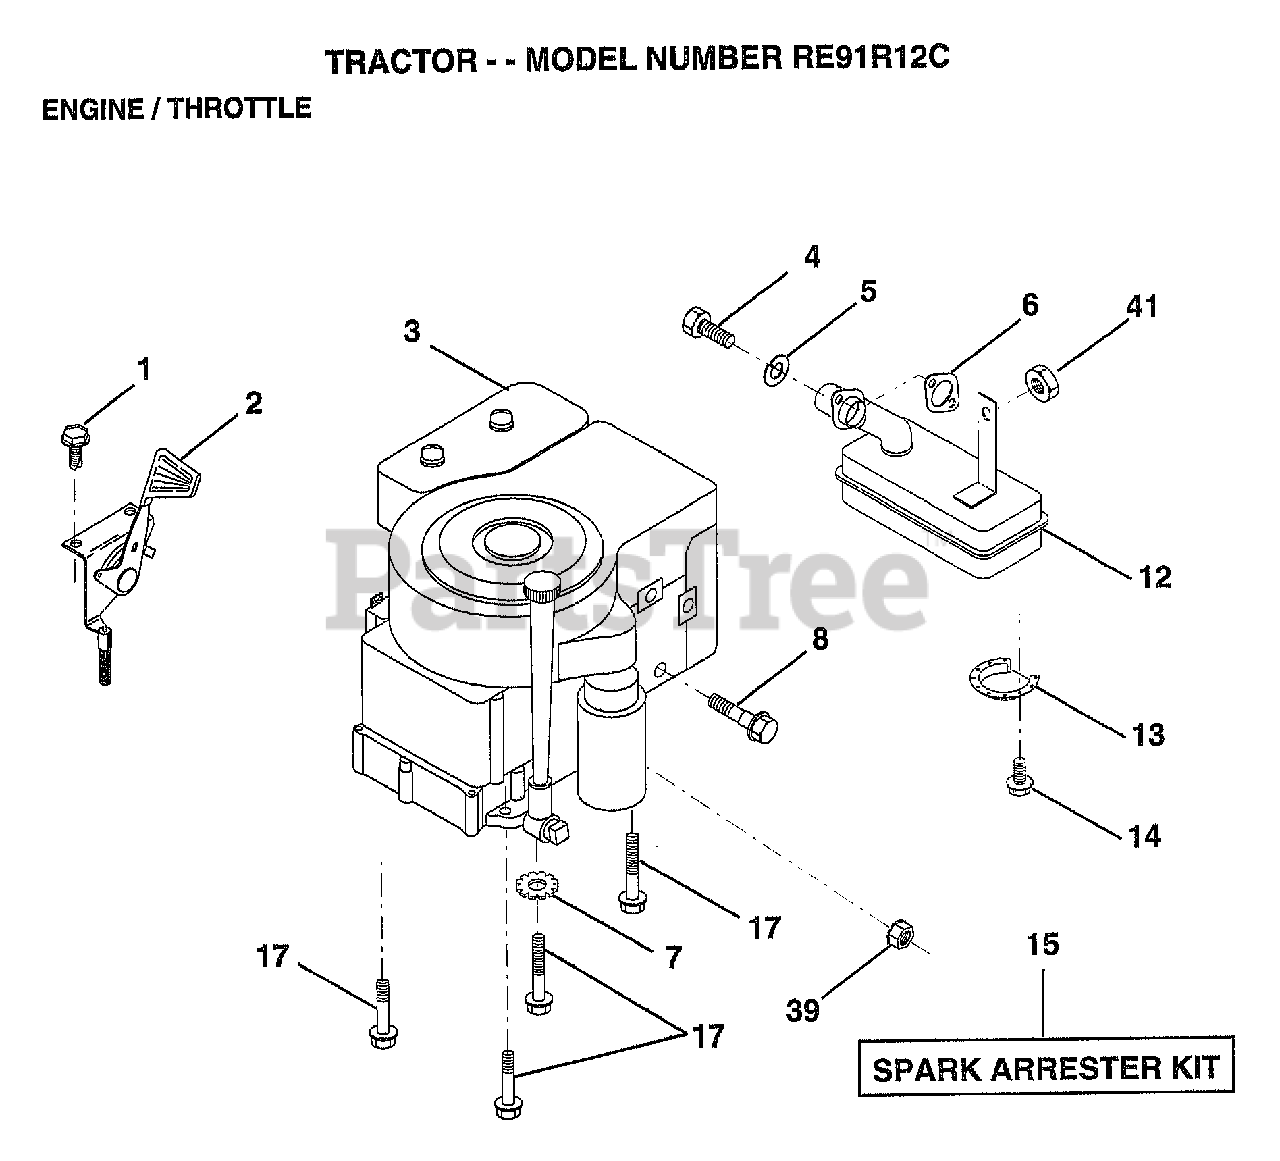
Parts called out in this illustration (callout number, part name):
1	SCREW.1/4-20X1/2
2	"CONTROL,THROTTLE"
4	SCREW HEX HD CAP
5	LOCKWASHER
7	LOCKWASHER
8	SHOULDER BOLT ST
12	MUFFLER-TECH 13HP
13	DEFLECTOR.222573
17	SCREW LT
39	NUT
41	"NUT HEX,LOCK,FLAN"
